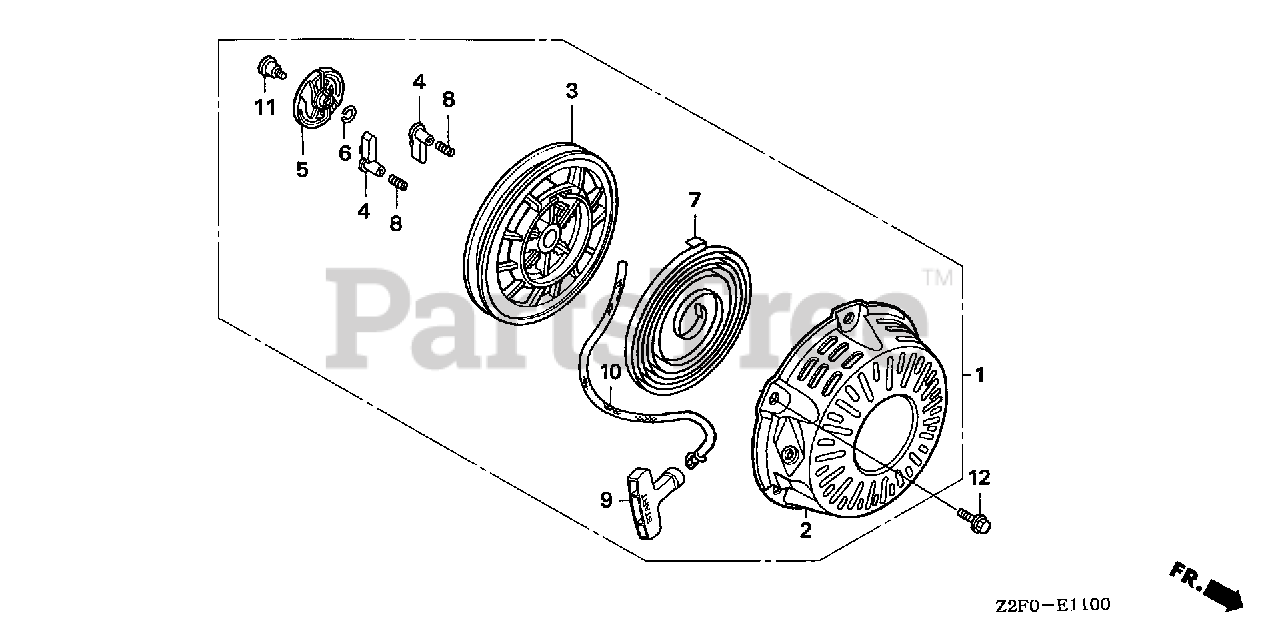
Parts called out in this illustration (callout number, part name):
1	STARTER ASSY., RECOIL *R280* (TURFCO) (POWER RED)
2	CASE, RECOIL STARTER *R280* (POWER RED)
3	REEL, RECOIL STARTER (NATURAL)
4	RATCHET, STARTER
5	GUIDE, RATCHET
6	SPRING, FRICTION
7	SPRING, RECOIL STARTER
8	SPRING, RETURN
9	GRIP, STARTER
9	KNOB, RECOIL SRARTER
10	ROPE, RECOIL STARTER (NA USE ALT:08550-ZG921-11)
11	SCREW, SETTING
12	BOLT, FLANGE (6X10)
